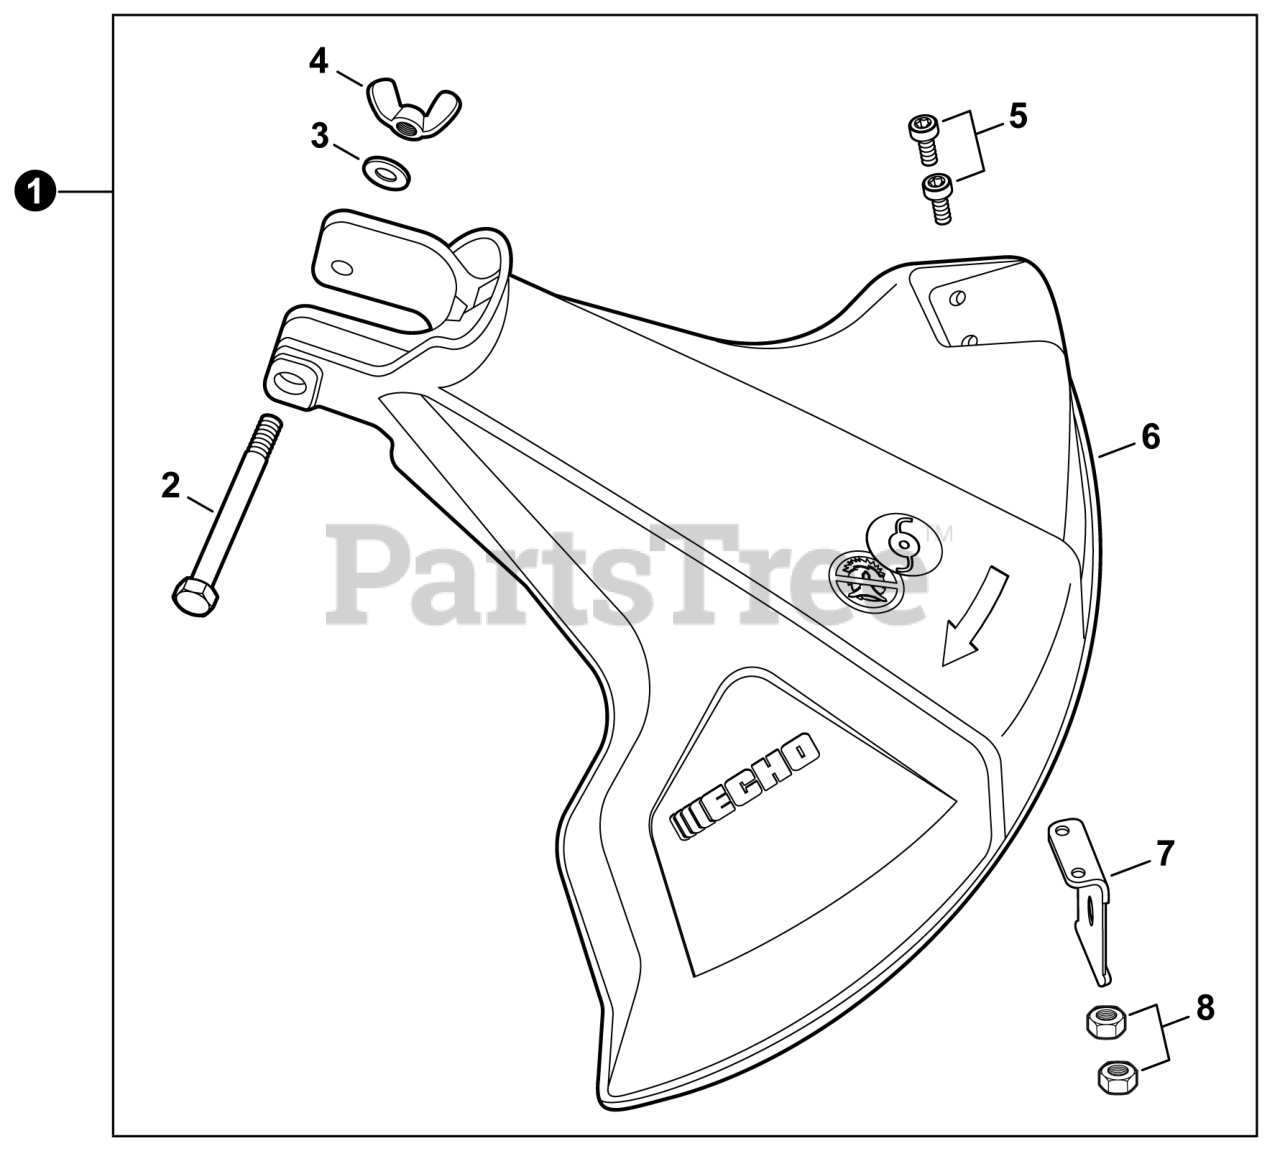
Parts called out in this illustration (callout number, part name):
1	SHIELD ASSY, DEBRIS
2	BOLT 1/4"-20x2"
3	WASHER, 1/4"
4	NUT, WING 1/4"-20
5	BOLT, TORX 5x12
6	SHIELD, DEBRIS
7	CUTTER, LINE
